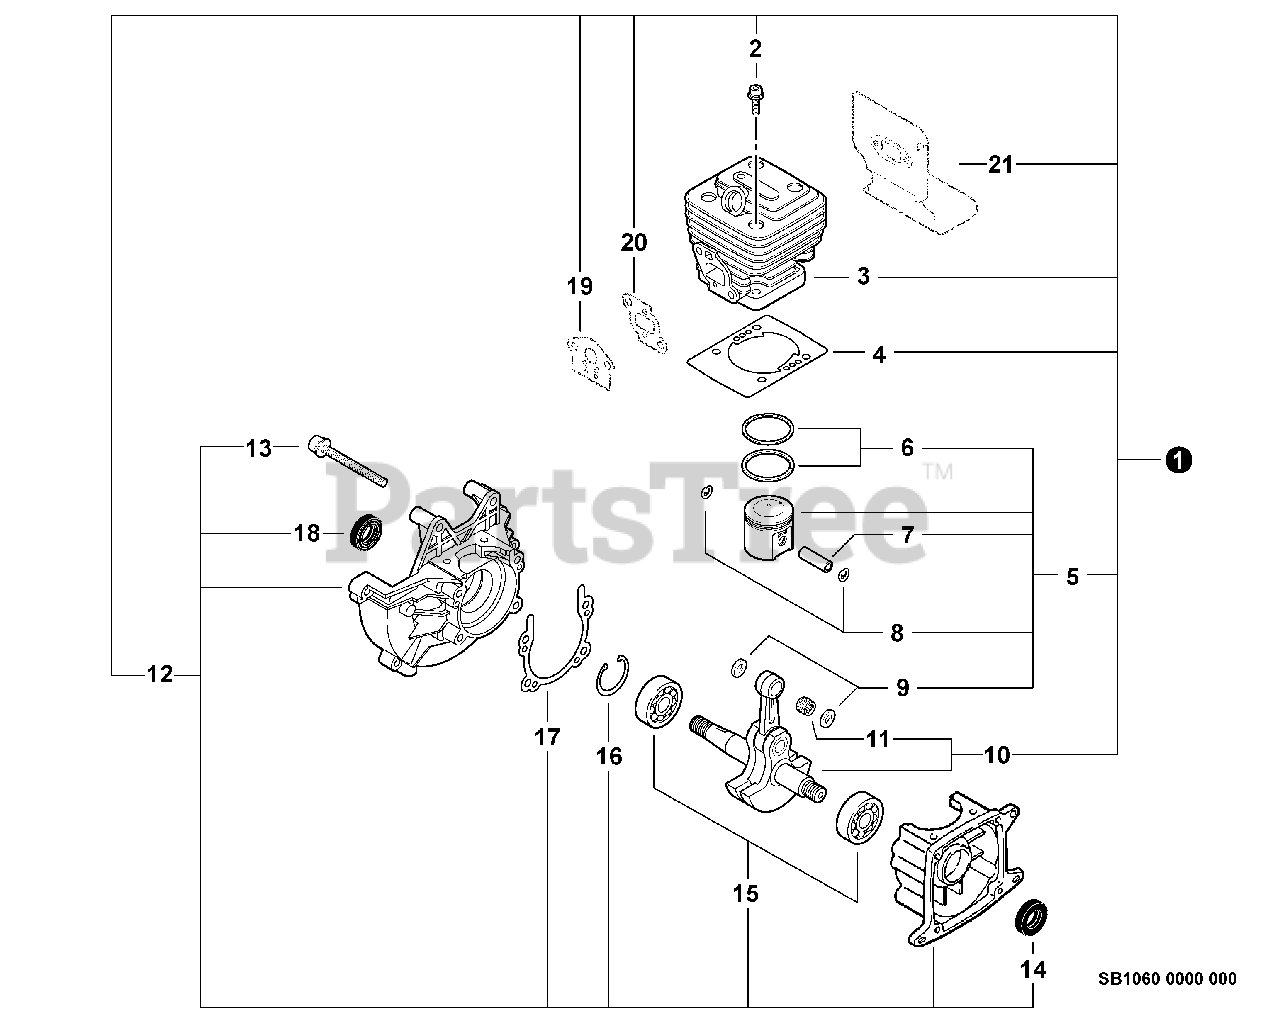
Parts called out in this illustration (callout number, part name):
1	SHORT BLOCK
2	BOLT 5×22
3	CYLINDER
4	GASKET, CYLINDER
5	PISTON KIT
6	RING, PISTON
7	PIN, PISTON
8	RING, SNAP
9	WASHER, THRUST
10	CRANKSHAFT ASSY
11	BEARING, NEEDLE 8
12	CRANKCASE ASSY
13	BOLT 5×25
14	SEAL, OIL 12
15	BEARING, BALL 6001
16	RING, SNAP 28
17	GASKET, CRANKCASE
18	SEAL, OIL 12
19	GASKET, INTAKE
20	GASKET, INTAKE
21	SHIELD, EXHAUST
